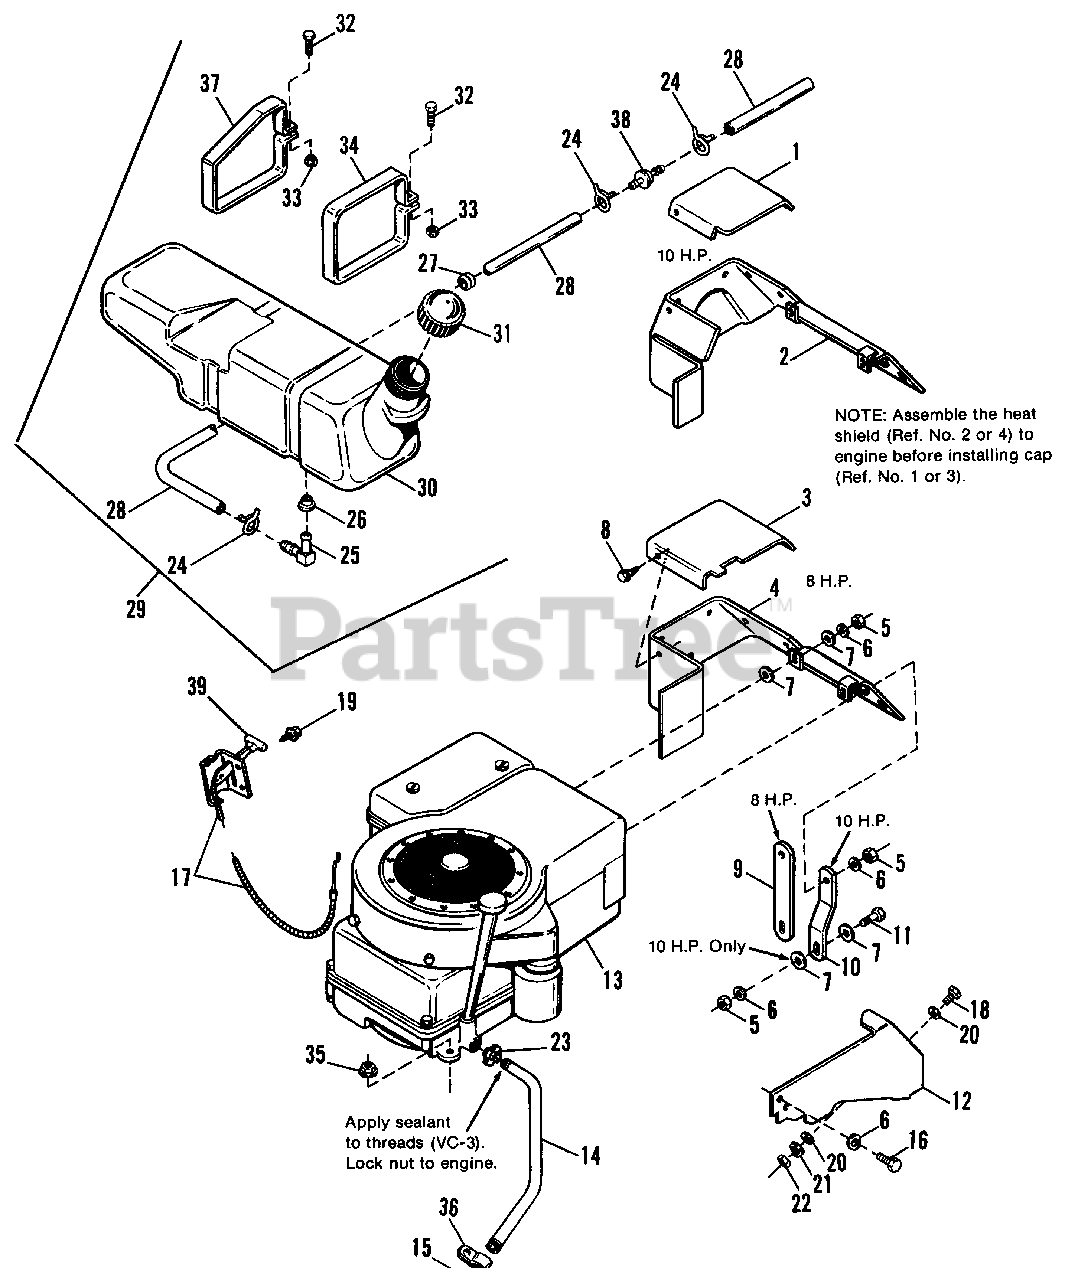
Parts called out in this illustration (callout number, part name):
1	CAP, Heat Shield (10 HP Only)
2	SHIELD ASSY., Heat (10 HP Only)
3	CAP, Heat Shield (8 HP Only)
4	SHIELD ASSY., Heat (8 HP Only)
5	NUT, Hex, 5/16-18
6	LOCKWASHER, 5/16-18
7	WASHER, Plain, 5/16
8	SCREW, Hex, Thd. Forming, #10 x 3/8
9	STRAP, Cylinder Head (8 HP Only)
10	STRAP, Cylinder Head (10 HP Only)
11	CAPSCREW, Hex, 5/16-18 x 1-1/2
12	SHIELD, Heat
13	ENGINE, 8 HP Elec. Start ENGINE, 10 HP Elec. Start
16	CAPSCREW, 5/16-18 x 3/4
17	CONTROL, Throttle
18	CAPSCREW, 1/4-20 x 3/4
19	SCREW, Hex, Taptite, 1/4-20 x 3/8
20	WASHER, 1/4
21	LOCKWASHER, 1/4
22	NUT, Hex, 1/4-20
23	LOCKNUT, Conduit, 3/8
24	CLAMP, HOSE
25	ELBOW, 90 Fuel Tank
26	BUSHING, Fuel Tank
29	FUEL TANK ASSY. (Incl. Ref. Nos. 24, 25, 26, 30, 37 & 38 )
31	GAS CAP, Vented
32	SCREW, 1/4-20 x 1-3/4
33	NUT, Center Lock, 1/4-20
34	STRAP, Fuel Tank
35	NUT, Hex, Full, 3/8-16
36	CLAMP, Tube
37	STRAP, Fuel Tank
38	FILTER, Fuel
39	KNOB, Push On
